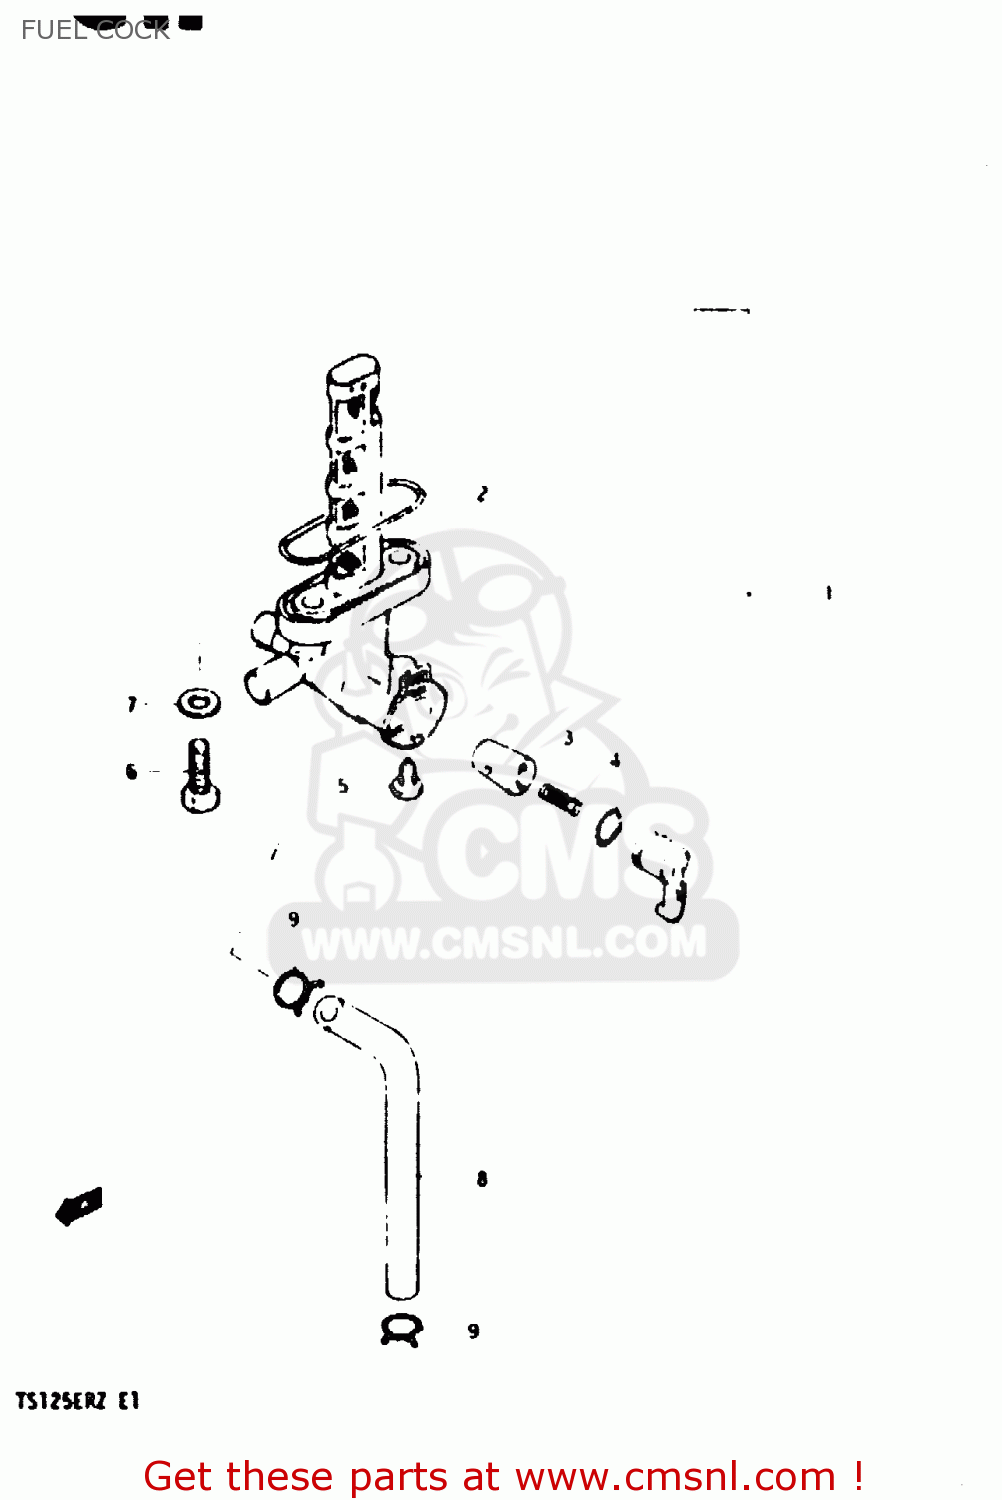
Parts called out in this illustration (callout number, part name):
1	COCK ASSY, FUEL
2	O RING,FUEL COCK
3	SPRING
4	O-RING
5	SCREW
6	BOLT(6X20)
7	GASKET
8	HOSE
9	CLIP
